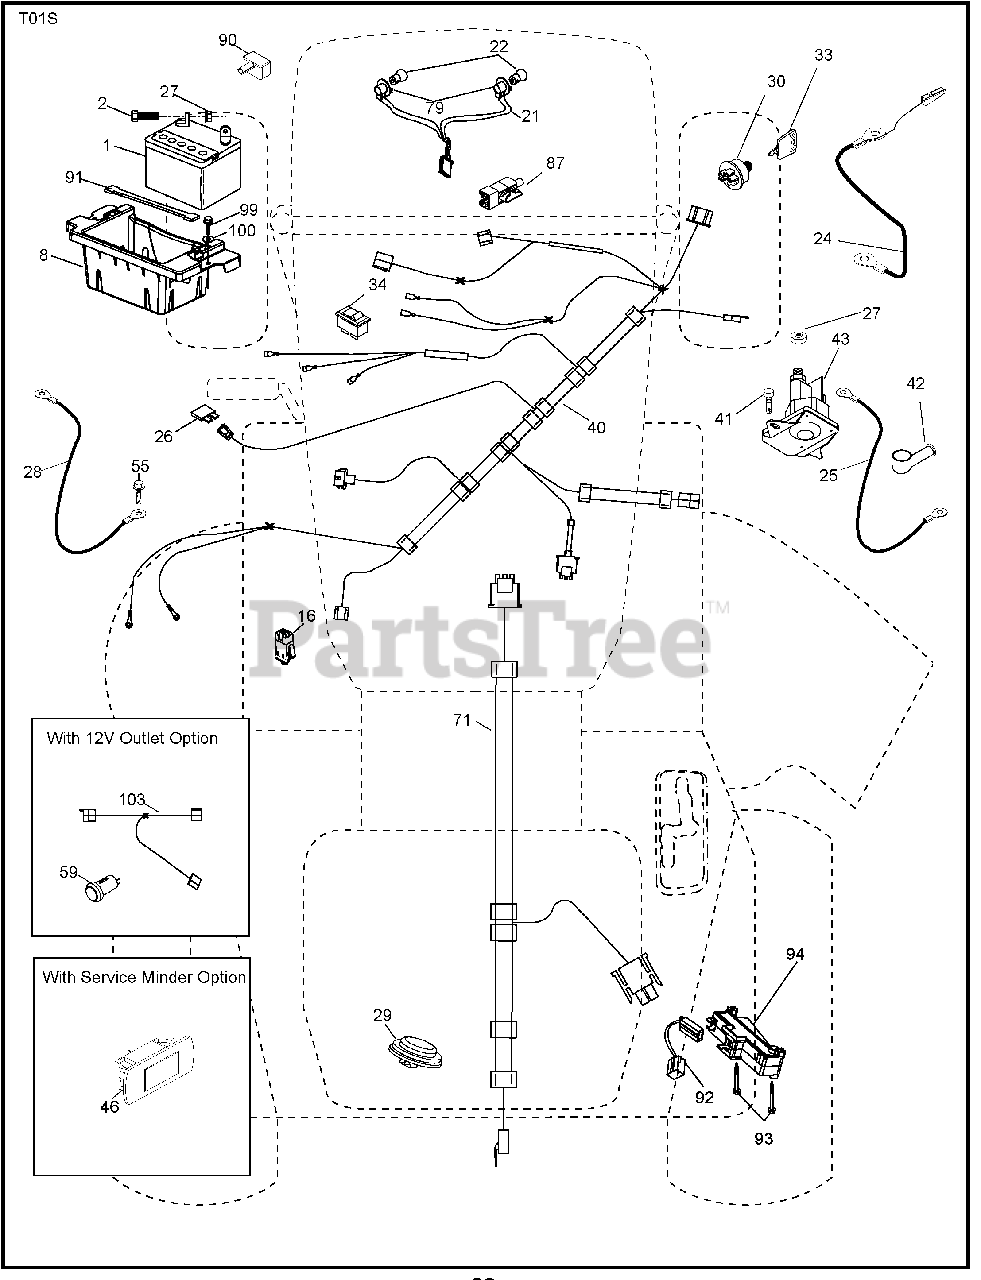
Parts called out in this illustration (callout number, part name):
1	Battery
2	Bolt Hex Head 1/4-20 x 3/4
8	Box Battery
16	Switch Interlock Push-In
21	Harness Socket Light w/4152J
22	Bulb Light
24	Cable Battery
25	Cable Starter
27	Nut Keps Hex 1/4-20 unc
28	Cable, Ground
29	Switch, Seat
30	Switch, Ign
34	Switch Light/Reset
40	Harness Ign. Dash
41	Screw Thd Cut 1/4-20 x 1/2
42	Cover, Terminal
43	Solenoid
55	Screw Thdrol 5/16-18 x 3/4
71	Harness Chassis
79	Socket Asm Bulb Twistlock
87	Switch Interlock Clutch Cable
90	Cover, Terminal Battery
91	Strap Battery Mount Front
92	Harness Pigtail Reverse Switch
93	Screw Plastite 10-14 x 2.0
94	Module Reverse ROS
99	Screw Hexwsh Thdrol 1/4-20 x 3/4
100	Washer 9/32 x 7/8 x 16 Ga.
